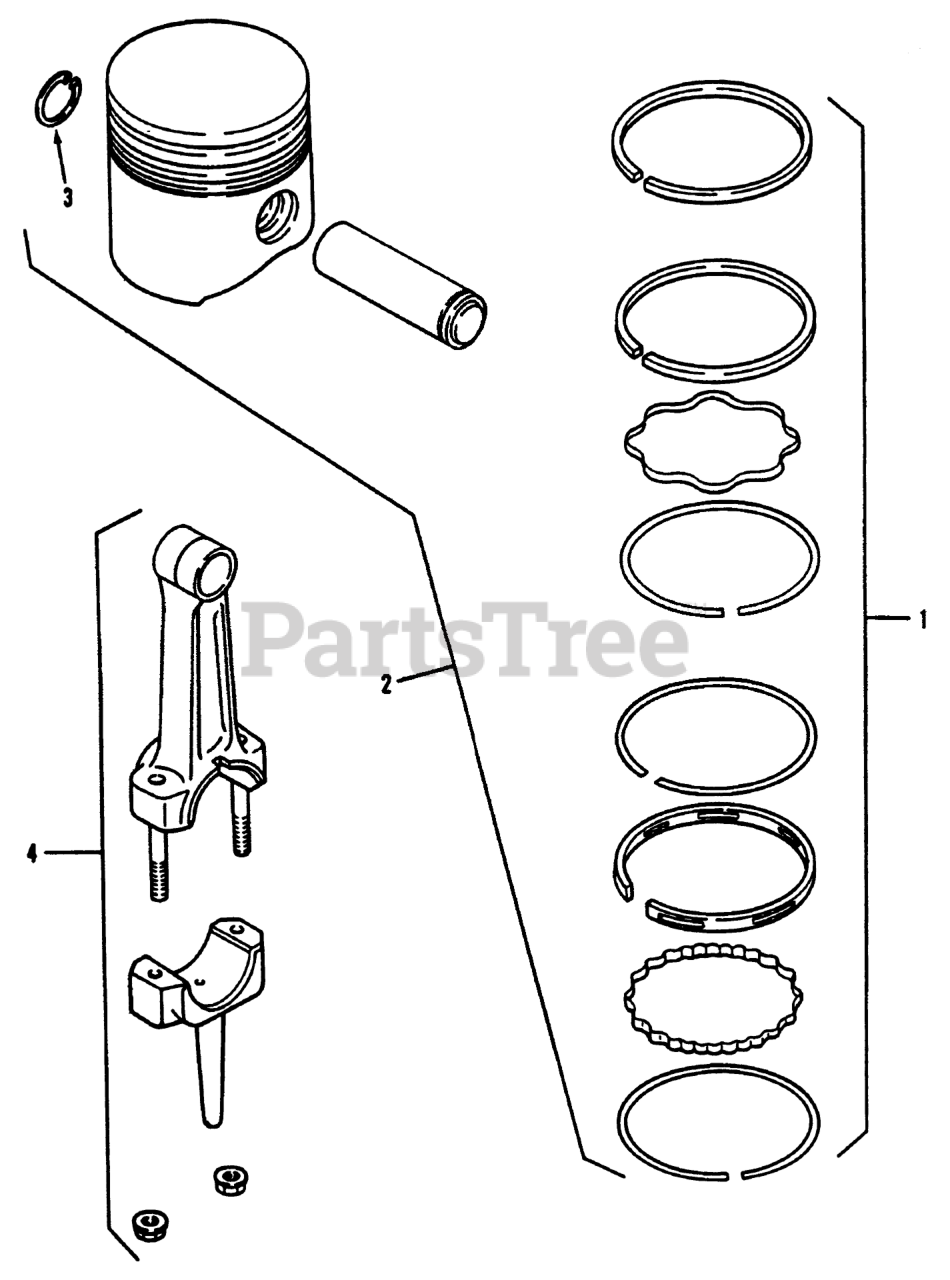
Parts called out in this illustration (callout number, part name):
1	Set-Ring, Std. &.003
2	Piston w/Ring Set Std.
3	Piston Pin Retainer
4	Rod-Connecting Std.
